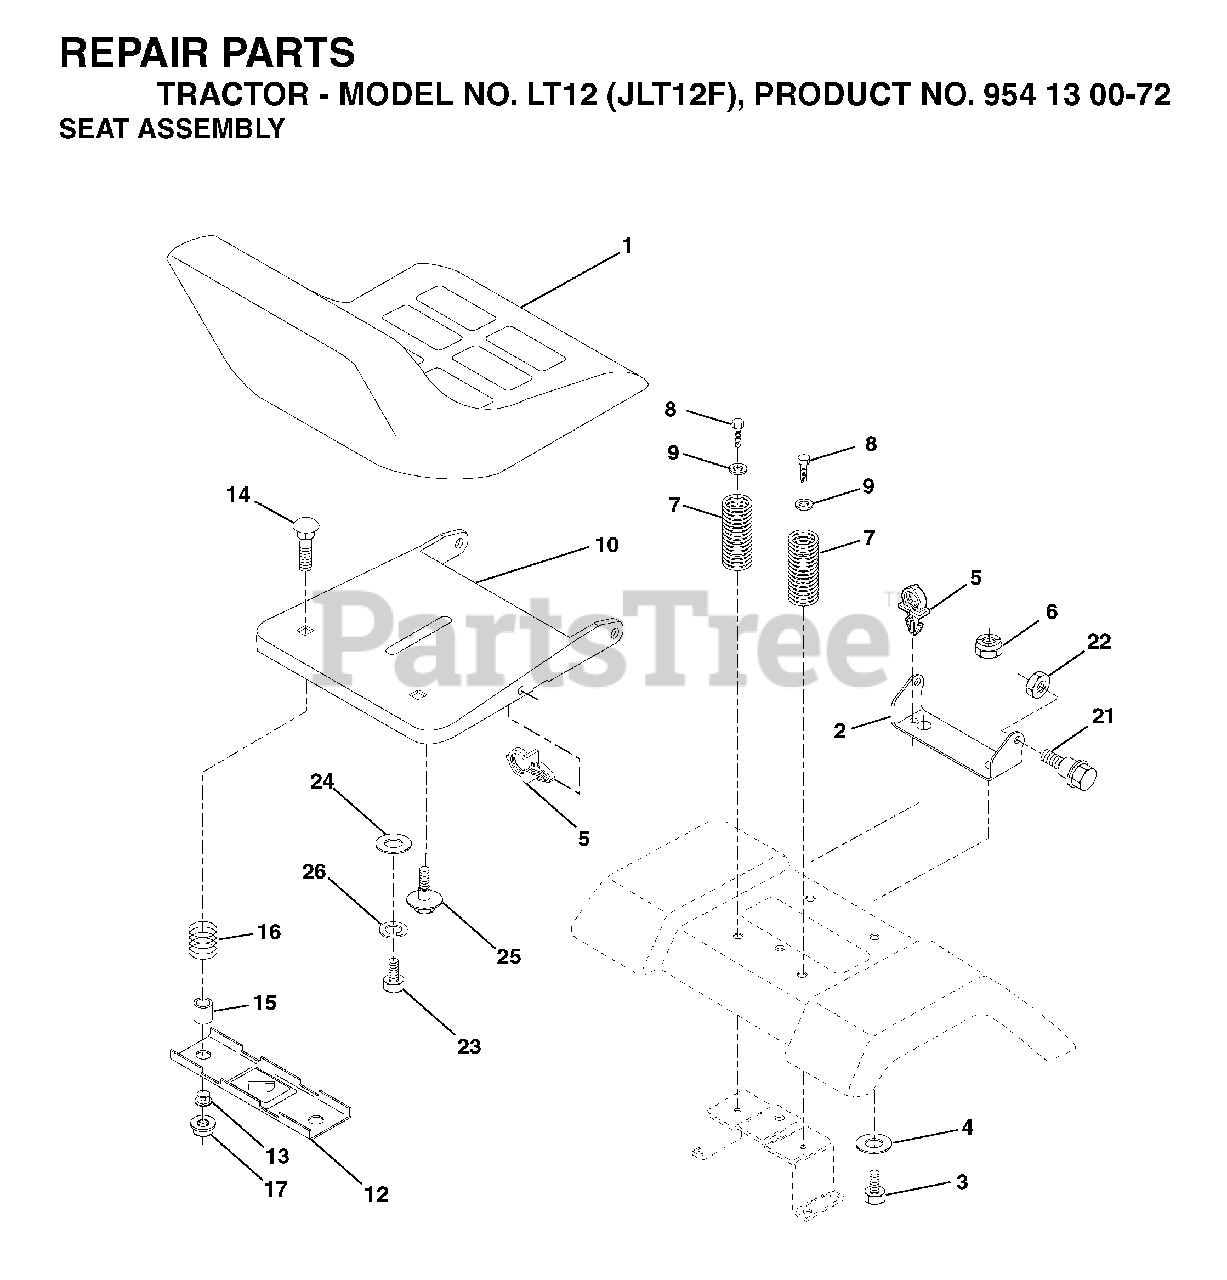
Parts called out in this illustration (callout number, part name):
1	SEAT
2	SEAT PIVOT BRKT
4	WASHER PM
5	PUSH CLIP
6	NUT
7	SPRING COMPRESSION
8	SCREW 3/8-16X1
9	WASHER
10	PAN SEAT
12	BRKT SWITCH
14	BOLT.ROUND.HEAD.SQUARE.NECK
15	SPACER SPLIT 28X.96
17	NUT T
21	BOLT.SHOULDER.5/16-18
22	NUT.71038.31-18.HEX.NYLOCK
23	BOLT.HEX.BLACK
25	BOLT,SHOULD
26	LOCKWASHER
